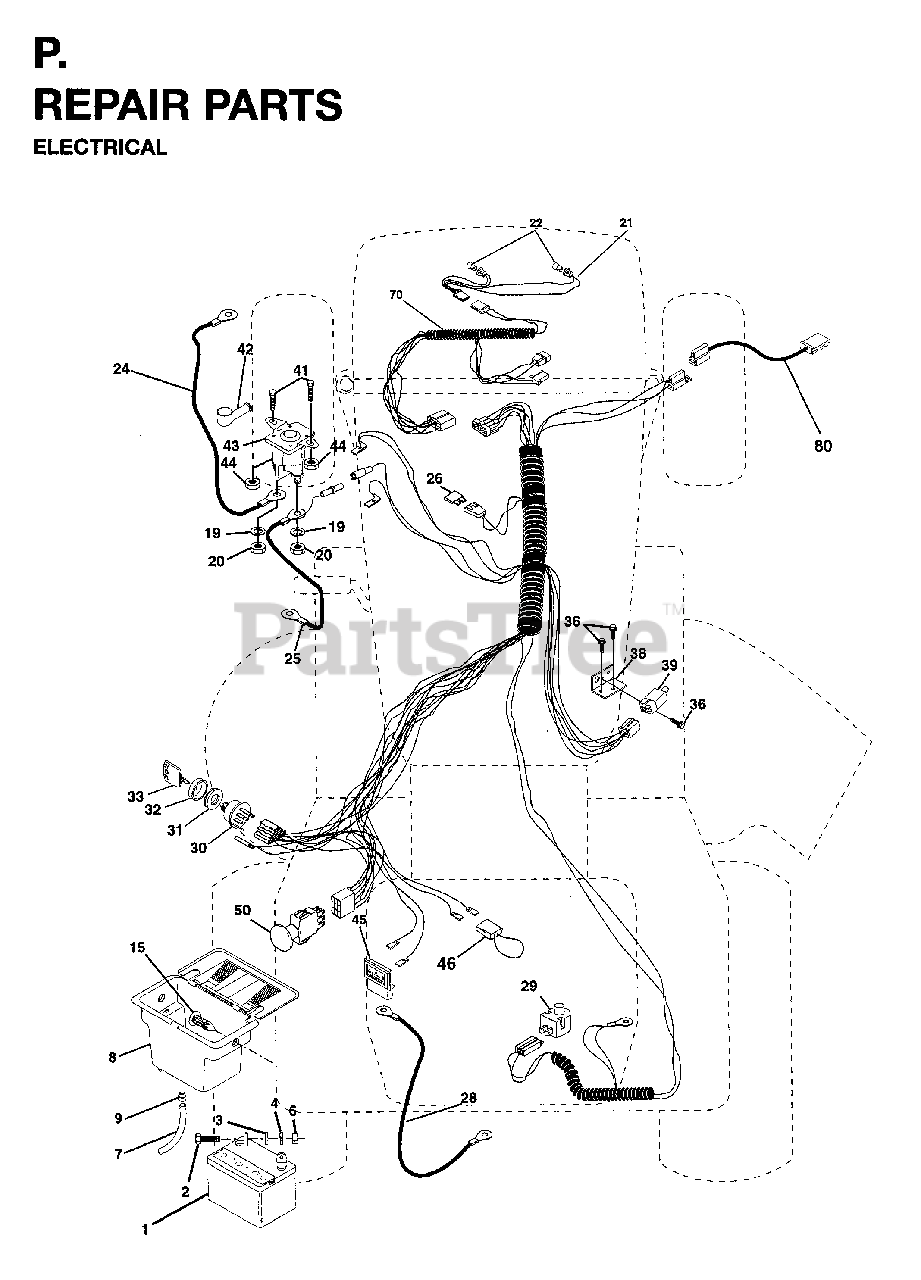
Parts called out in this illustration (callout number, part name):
1	BATTERY
4	LOCKWASHER
6	NUT
7	TUBE BATTERY DRAIN
8	BATTERY CASE
9	HOSE CLAMP T
15	FASTERER SNAP-IN
19	LOCKWASHER
20	NUT
21	HARNESS ASM HDLIG
22	LIGHTBULB
24	BATTERY CABLE
25	CABLE BATTERY
28	CABLE T
29	SWITCH SEAT
30	SWITCH.IGNITION.4.POSITION
31	NUT IGNITION
32	COVER SWITCH KEY
33	KEY SET
38	SWITCH BRACKET
39	SWITCH INTERLOCKT
40	HARNESS IGN ELEC P/L
41	BOLT
42	TERMINAL COVER
43	KIT SOLENOID .95
44	NUT.CROWNLOCK.1/4
50	SWITCH-PTO
52	WIRE PROTECTION LOOP
70	HARNESS ENGINE
80	HARNESS, CLUTCH
